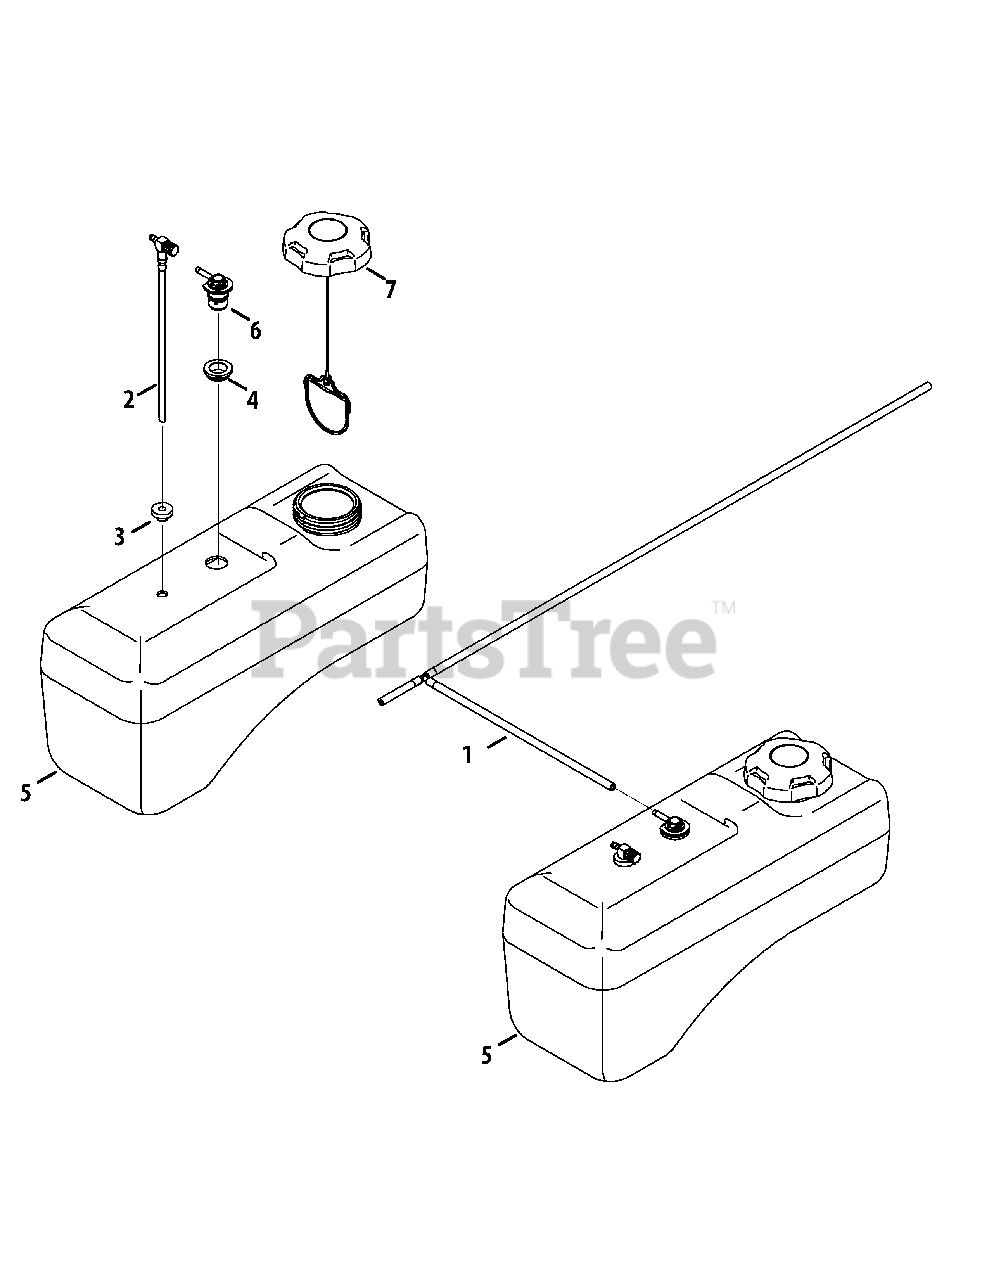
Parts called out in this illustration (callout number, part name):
1	Rollover Vent Hose Assembly
2	Pick-Up Fuel Fitting Valve
3	Fuel Tank Bushing
4	Rubber Grommet
6	Fuel Rollover Valve
